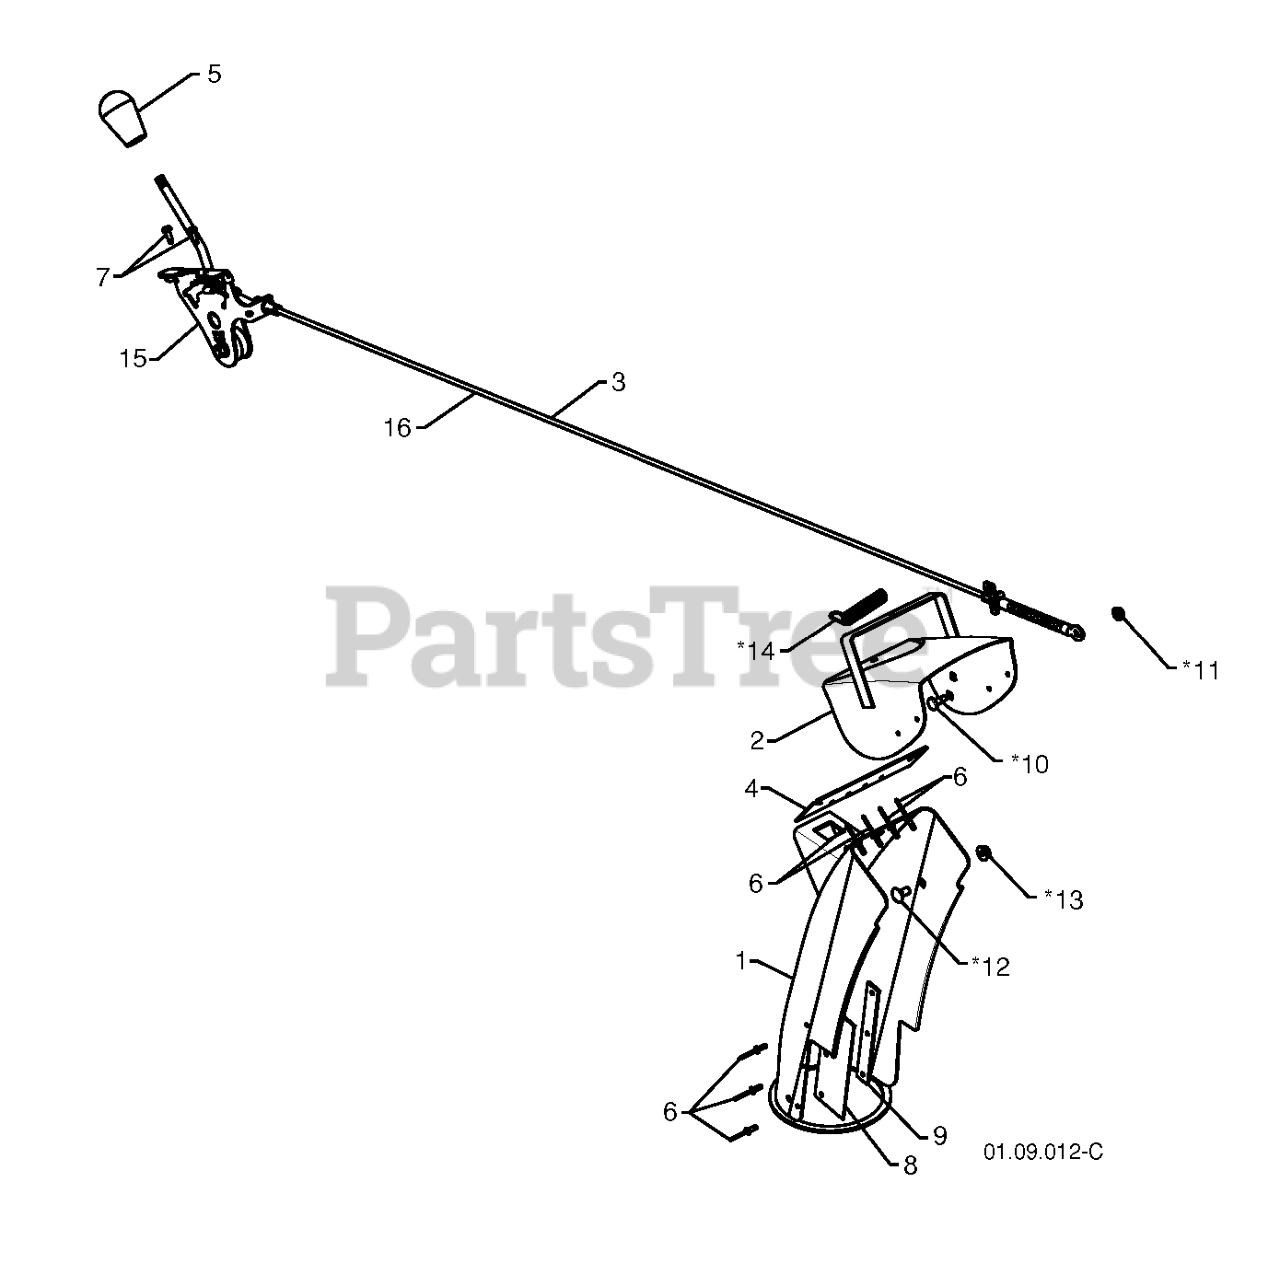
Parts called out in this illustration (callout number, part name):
1	RP CHUTE.WELDMENT.PNT.ORANGE
2	DEFLECTOR.WELDMENT.PNT.ORANGE
3	CONTROL.ASM.DEFLECTOR
4	SEAL.DEFLECTOR
5	KNOB LEVER, BLACK
6	RIVET BLIND
7	SCREW #10-24 X 5/8
8	SHIELD.SNOW.CHUTE
9	RP STRAP.SHEILD.RETAINER
10	BOLT, SHOULDER
11	NUT.HEX.FLANGE.1/4
12	BOLT
13	NUT.LOCK.5/16-18
14	SPRING.DEFLECTOR.REM.CHUTE
15	RP CNTRL.HEAD.ASSEM.DEFLECTOR
16	SERVICE.CHUTE.DEF.CBL.GRY
